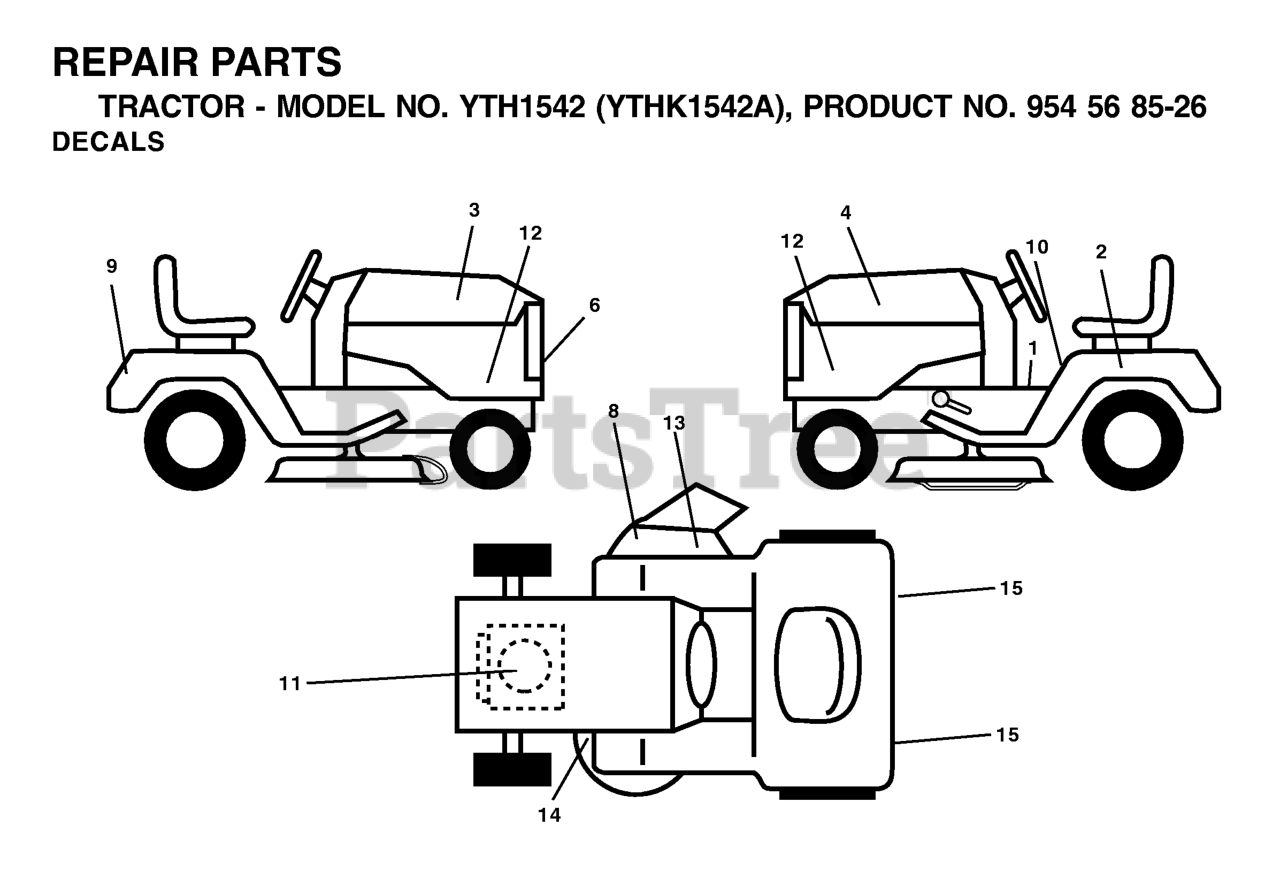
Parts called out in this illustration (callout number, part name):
2	DECAL BTRY SYMBOLS
6	DECAL.GRILLE.HUSQ
8	DECAL.WARN.KEEP.HAND.AWAY
9	DECAL, FENDER
10	DECAL FENDER DANGER
13	DECAL DECK "B" 42"
14	DECAL V BELT SCHEMATIC
15	REFLECTOR-TAIL YT
